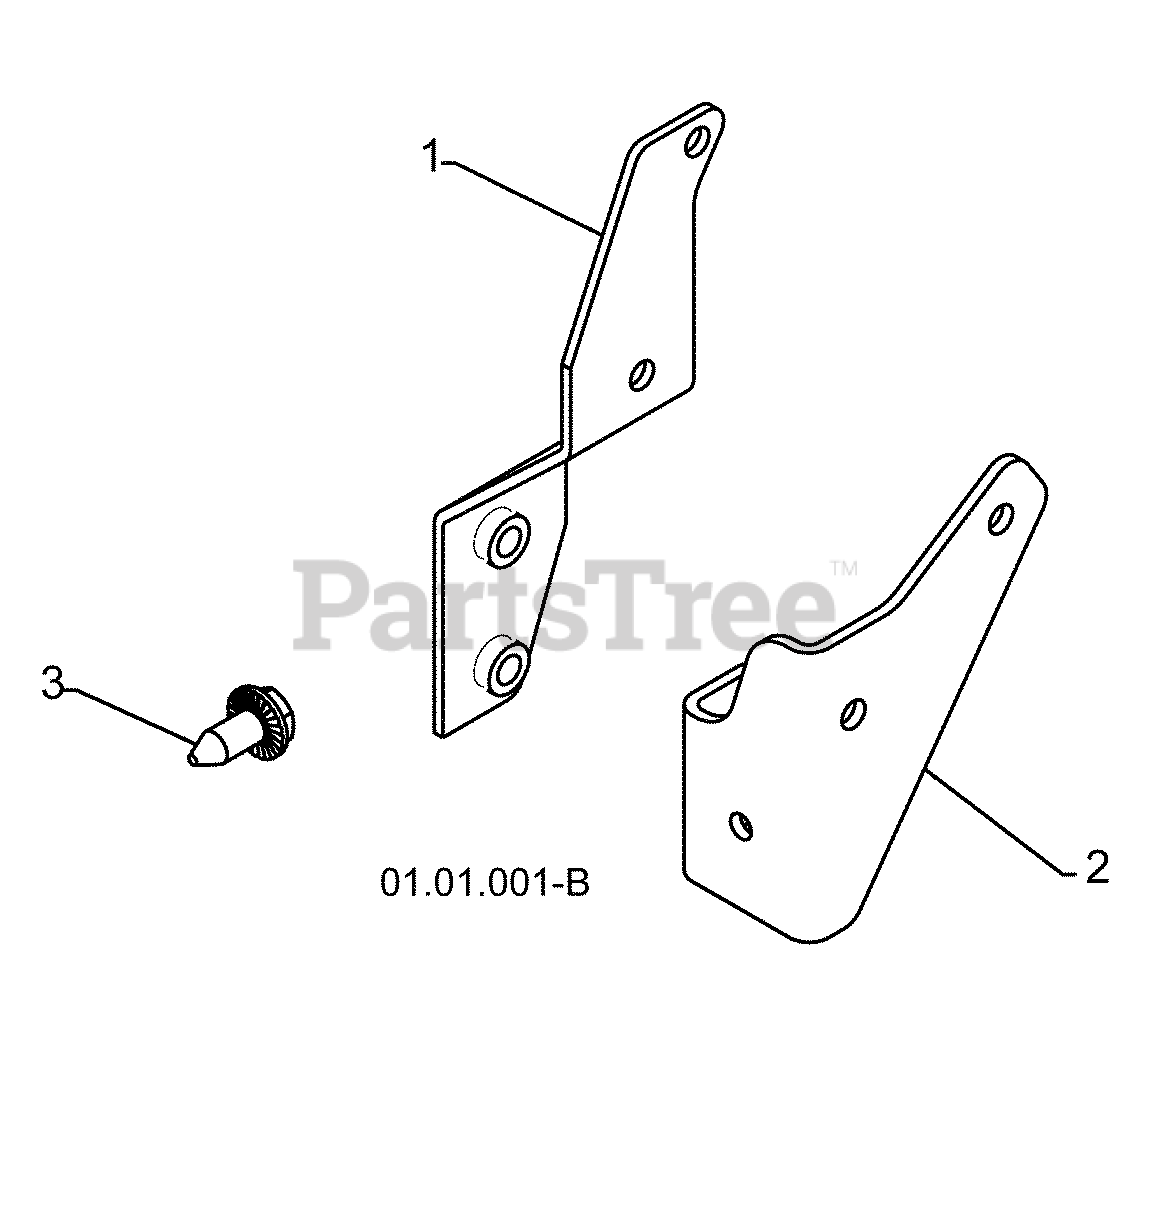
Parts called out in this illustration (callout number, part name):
1	TORQUE STRAP
2	ANTI ROTATE BRACKET
3	SCREW 5/16-18 X .750
